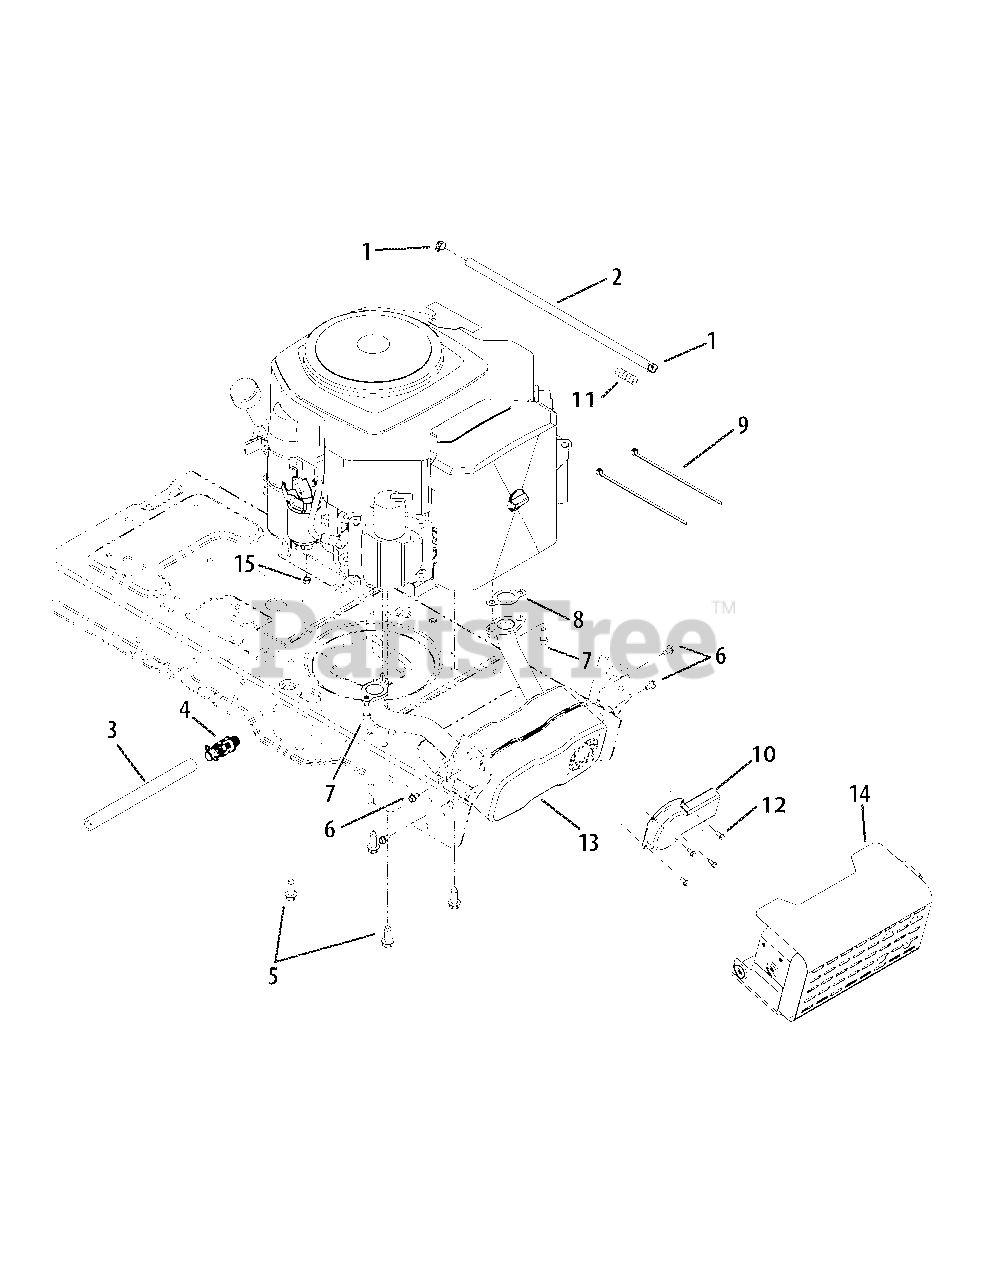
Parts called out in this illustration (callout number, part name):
1	Hose Clamp
2	Fuel Line 16" Lg.
3	Oil Drain Hose
4	Oil Drain
5	TT Screw 3/8-16 x 1.00
6	Hex Wash S-Tapp Scr 1/4-20 x .50
7	Scr. 5/16-18 x .75
8	Exhaust Gasket
9	Cable Tie
10	Long Muffler Deflector
11	Vent Hose (optional)
12	Hex AB Scr #8-18 x .50
13	Muffler
14	Muffler Shield Assembly
15	Hex Sems Nut 1/4-20
